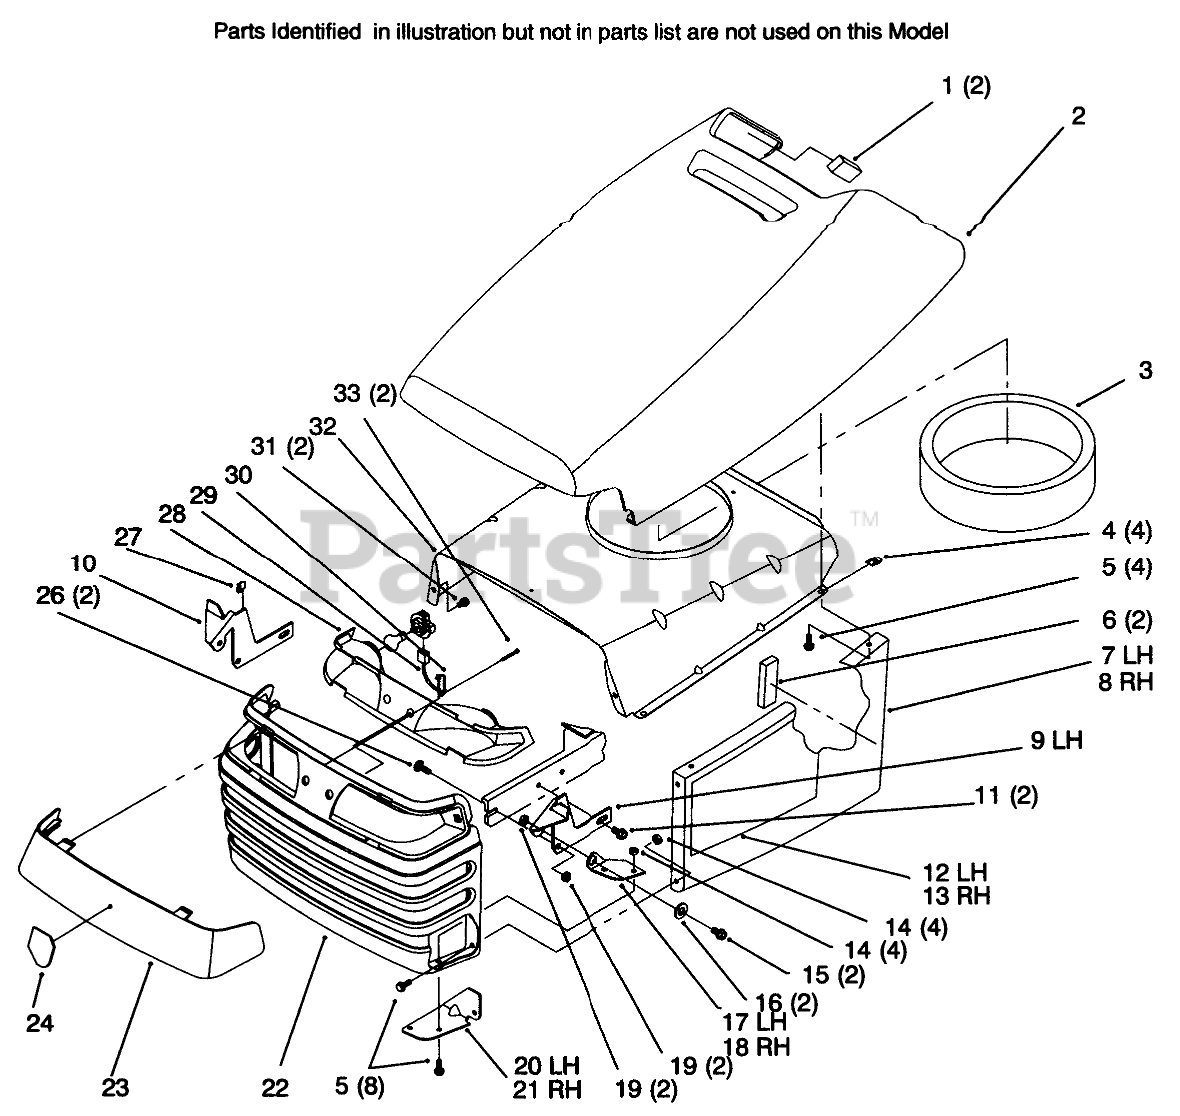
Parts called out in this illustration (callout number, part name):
1	FOAM-HOOD
2	HOOD ASM
3	SEAL-AIR INLET
5	SCREW-HWH
6	FOAM-SIDEPANEL
7	HOOD-SIDE, LH
8	HOOD-SIDE, RH
9	BRACKET-HINGE, LH
10	BRACKET-HINGE, RH
11	SCREW-HWHTF
12	DECAL - LH HOOD
13	DECAL - RH HOOD
14	NUT-LOCK, HHF
15	SCREW-HH
16	BUSHING
17	HINGE-HOOD, LH
18	HINGE-HOOD, RH
19	NUT-LOCK, NI
20	BRACKET-HOOD HINGE, RH
21	BRACKET-HOOD HINGE, LH
22	Screen/Grill ASM
23	LENS - HEADLIGHT
24	EMBLEM-HORSEHEAD
26	BOLT-CARR
27	CLIP-RETAINER, WIRE
28	HEADLIGHT REFLECTOR ASM
29	HARNESS-WIRE, LIGHTS
30	TIE-CABLE
31	SCREW-PLASTITE
32	BAFFLE-HOOD, UPPER
